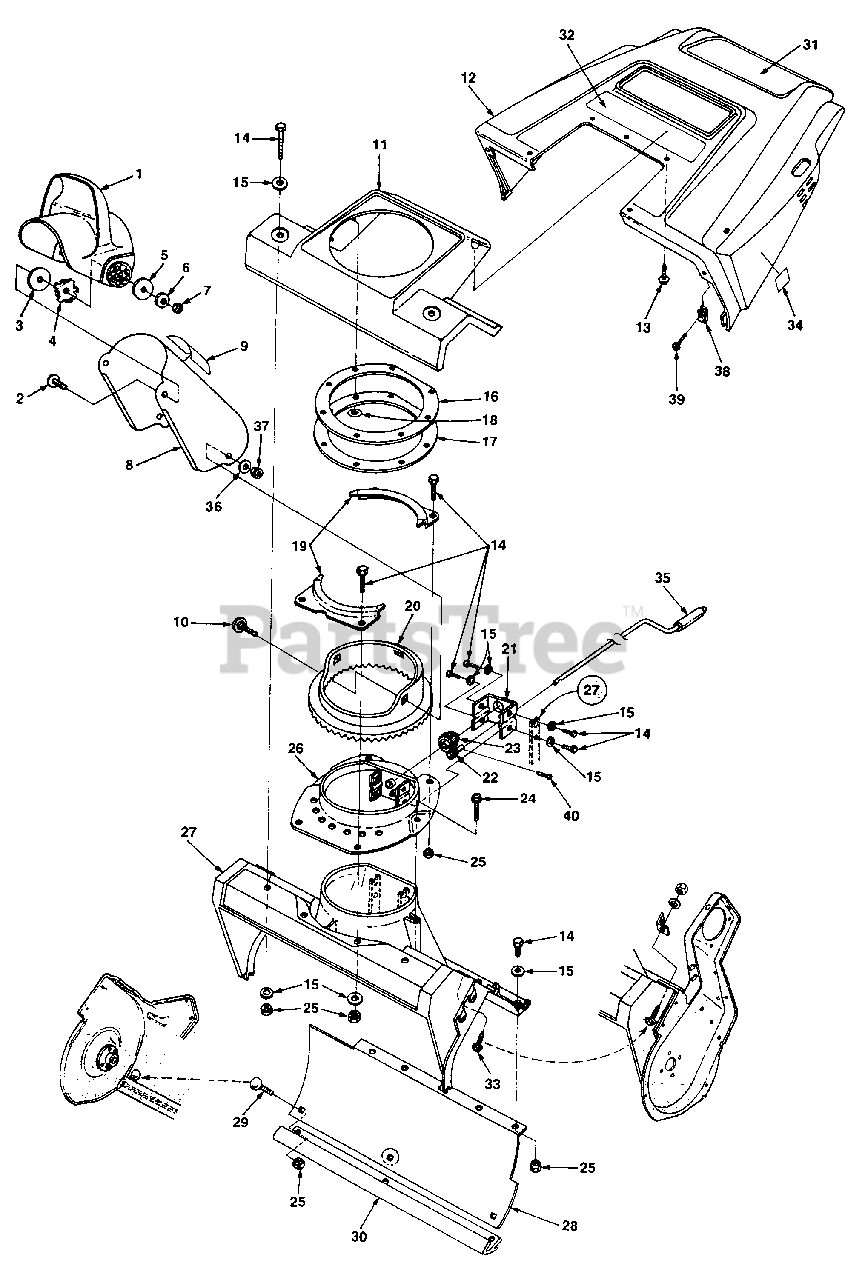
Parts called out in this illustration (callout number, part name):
1	DEFLECTOR
2	BOLT- Carr. 5/16-18 x 1
3	WASHER-Flat rubber
4	WASHER- Octagon
5	WASHER-Flat
6	WASHER-Belleville
7	NUT-Flange 5/16-18
8	CHUTE
9	DECAL-Warning
10	BOLT-Square neck 5/16-18 x 5/8
11	COWLING-Transition
12	COWLING-Upper
13	SCREW- Thd. forming #10 x 5/8
14	SCREW- Hex 1/4-20 x 3/4
15	WASHER- Plain 1/4
16	GASKET-Chute
17	RETAINER-Gasket
18	NUT-Push on
20	BASE-Chute
21	BRACKET-Gear
22	DRIVE-Gear
23	GEAR-Idler
24	SCREW-Plastite
25	NUT-Flange 1/4-20
26	BASE-Chute
27	HOUSING-Auger
29	BOLT- 1/4 x 3/4
31	DECAL-Console
32	DECAL-420
33	BOLT-Carr. 1/4-20 x 1/2
34	DECAL
35	SHAFT & HANDLE
36	WASHER-Lock 5/16
37	NUT-Hex 5/16-18
38	NUT-Speed
39	SCREW- 1O x 1 1/2
40	PIN- Cotter 1/8 dia.
